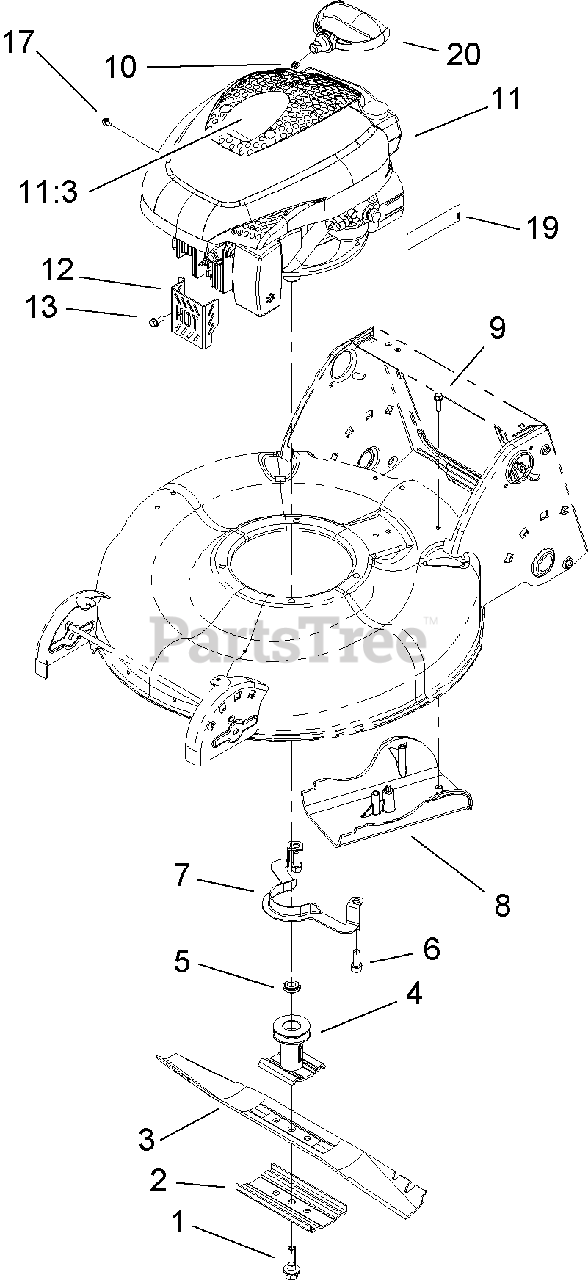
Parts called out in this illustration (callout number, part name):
1	BOLT-BLADE
2	SUPPORT-BLADE
3	BLADE-21 INCH
4	BLADE DRIVER ASM
5	Spacer-Driver
6	SCREW
8	COVER-BELT
9	SCREW-HWH
10	STOP-ROPE
11:3	DECAL-RECOIL
12	GUARD-MUFFLER
13	SCREW-HWH
17	SCREW-HWH
19	DECAL-PRIMER
20	HANDLE-RECOIL
